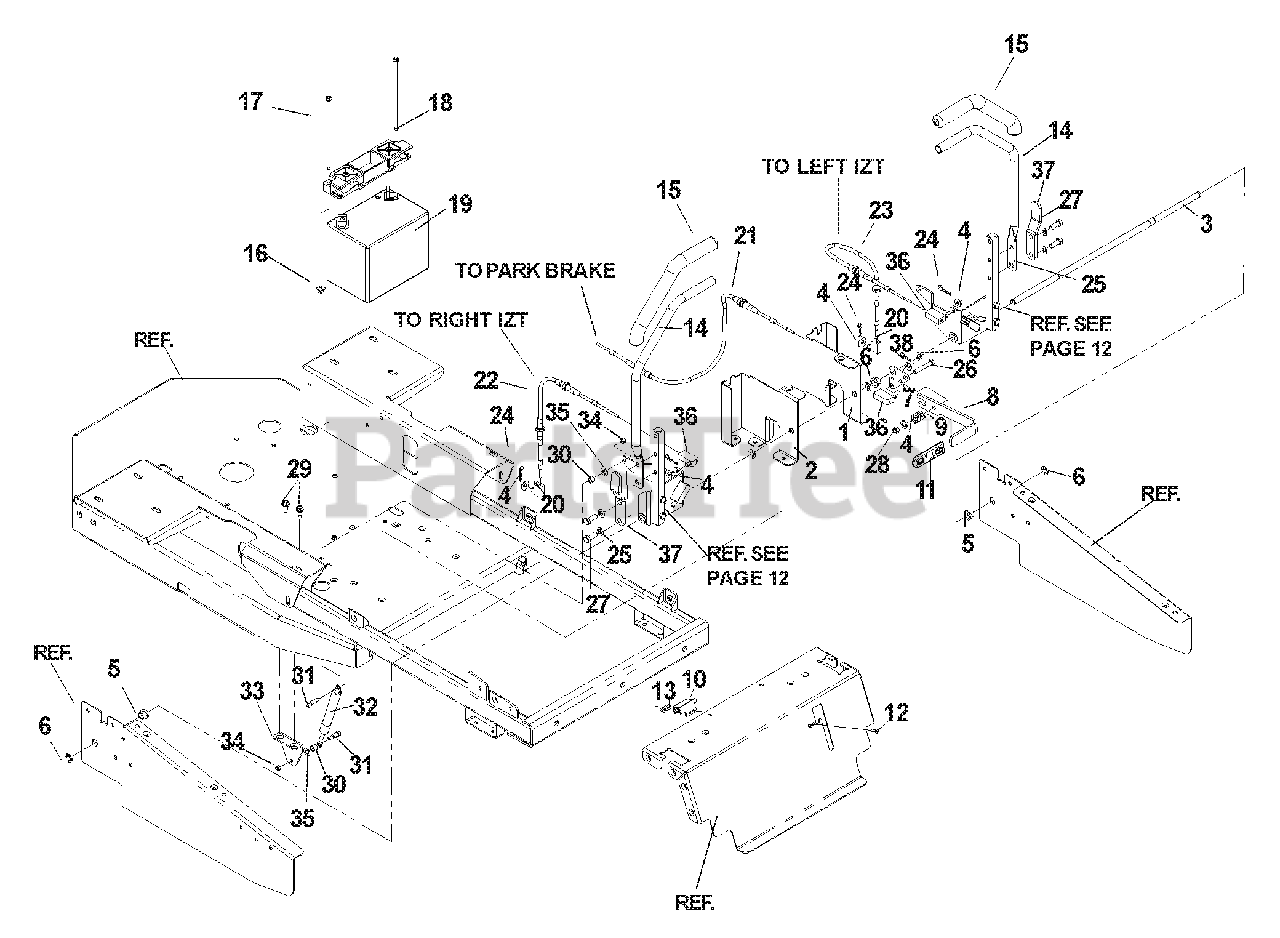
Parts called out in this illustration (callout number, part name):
1	BATTERY SUPPORT, LEFT
2	BATTERY SUPPORT, RIGHT
3	CONTROL PIVOT SHAFT
4	WASHER, 5/16 FLAT
5	BUSHING, NYLON FLANGED
6	E-RING, 1/2"
7	BRAKE LEVER
8	UPPER BRAKE LEVER
10	SWITCH N.C.
11	GRIP, PARK BRAKE
12	SCREW, #10-24 X 5/8 MACH.
13	TAPPED PLATE
14	CONTROL LEVER
15	DRIVE LEVER CUSHION
16	PUSH NUT, NYLON
17	BOLT, 1/4-20 X 7 1/2
18	BATTERY HOLD DOWN
19	BATTERY, DRY
20	LOWER CABLE END
21	CABLE, BRAKE
22	CABLE, RIGHT
23	CABLE, LEFT
24	COTTER, HAIRPIN
25	WASHER, 3/8 SPRING
26	HCS 5/16C X 2
27	HCS 3/8C X 1
28	NUT, 5/16C NYLOC
29	BOLT 5/16-18 X 3/4, THREAD FORMING
31	BOLT 5/16C X 5/8, SHLD
33	BRACKET, DAMPENER
34	NUT 1/4C, THIN NYLOC
36	UPPER CABLE END
38	WASHER, 5/16, SAE
